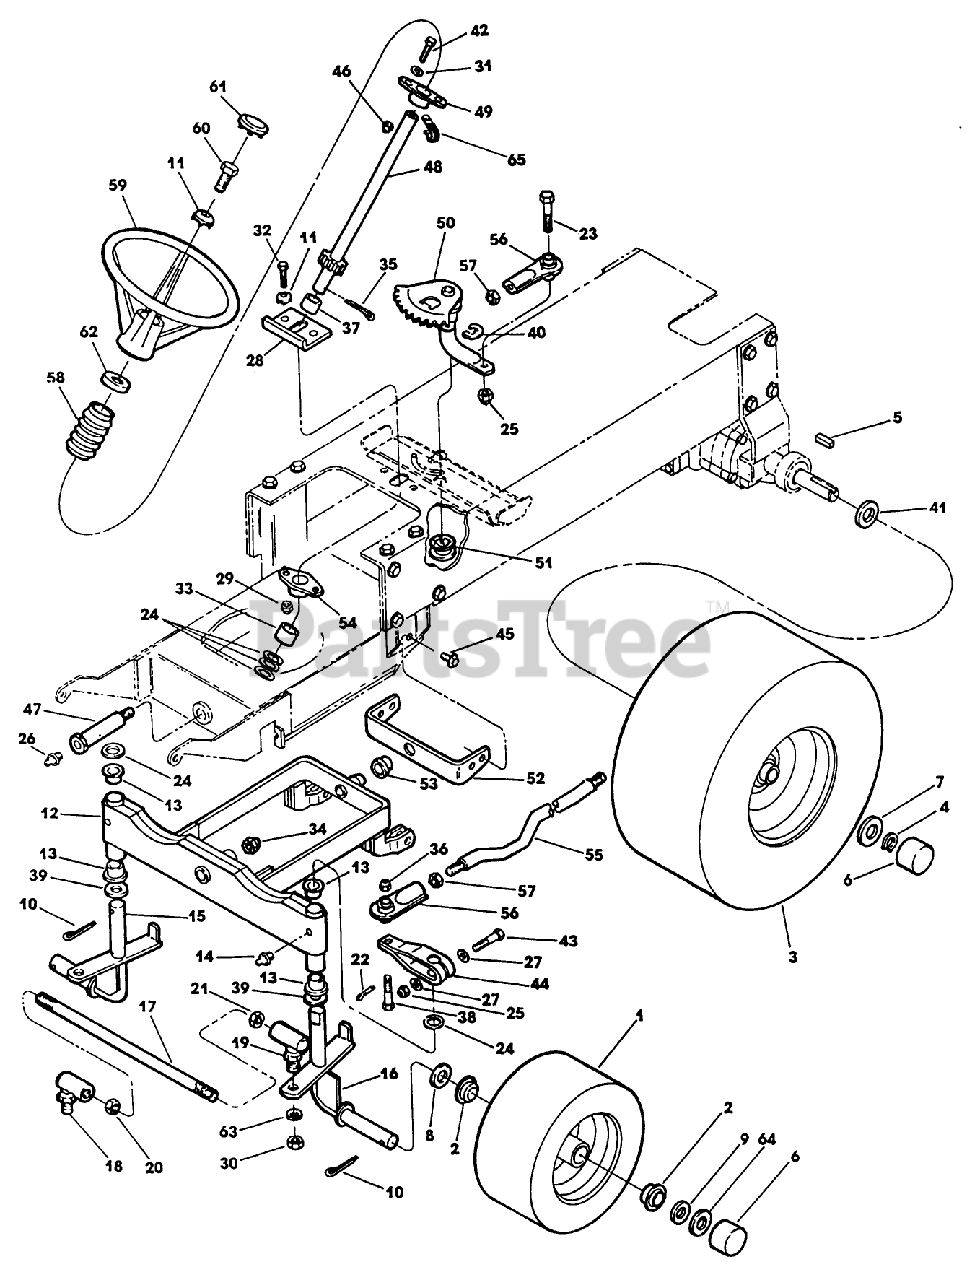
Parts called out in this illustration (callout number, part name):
5	KEY-SQUARE 1/4X1/4
9	WASHER
12	AXLE AY-FRONT
13	BEARING - BRONZE
16	SPINDLE ASM - LH
18	BALL JOINT, RH
19	BALL JOINT-LH
21	NUT HEX JAMB LH
24	SPACER
25	NUT-LOCKING
27	WASHER
29	NUT
30	HEX NUT
32	SCREW
34	NUT-HEX
37	SPACER
39	WASHER - THRUST
42	SCREW-HH
46	NUT-LOCK, CONE
49	BEARING AY.
56	BALL JOINT
57	NUT-HEX
60	SCREW - HEX
61	CAP
65	CLAMP - J EX
